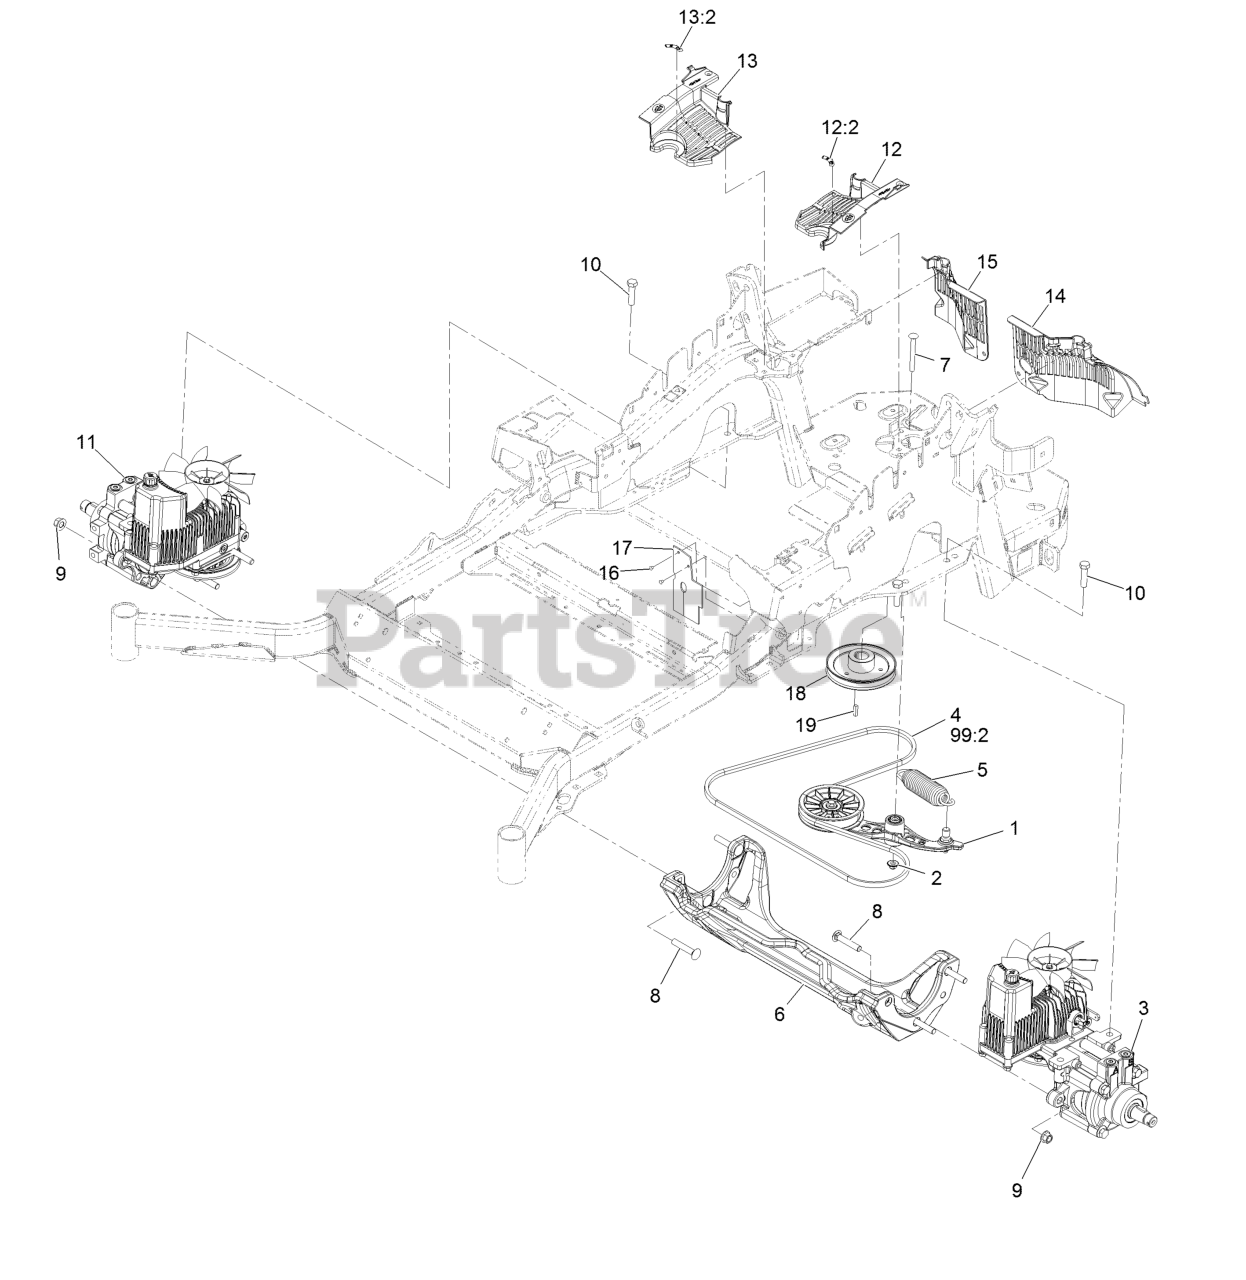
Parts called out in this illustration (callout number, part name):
1	Pump Idler ASM
2	Nut-Nyloc 3/8-16 Flg
3	LH Hydro ASM (16Cc W/ Shock)
4	Belt
5	Spring-Extension
6	Cradle-Hydro
7	Bolt-Carriage Shoulder 3/8-16 X 3 1/2
8	Screw-CARR
9	Nut-Lock 1/2-13
10	Screw-HH 1/2-13 X 1 1/4
11	RH Hydro ASM (16Cc W/ Shock)
12	LH Hydro Guard ASM
12:2	Decal-Oil, Hydro
13	RH Hydro Guard ASM
13:2	Decal-Oil, Hydro
14	Guard-Hydro, Rear (LH)
15	Guard-Hydro, Rear (RH)
16	Rivet 3/16 X 1/4
17	Deflector-Air Flow
18	Sheave
19	Key-Machine 1/4 X 1/4 X 1
99	Bottle-Oil, 32Oz Hydraulic
99	Filter-Hydro
99	Bottle,Oil 1 Gallon Hydraulic
99	Kit, Hydro Service
99:1	Bottle-Oil, 32Oz Hydraulic
99:2	Belt
99:3	Filter-Hydro
